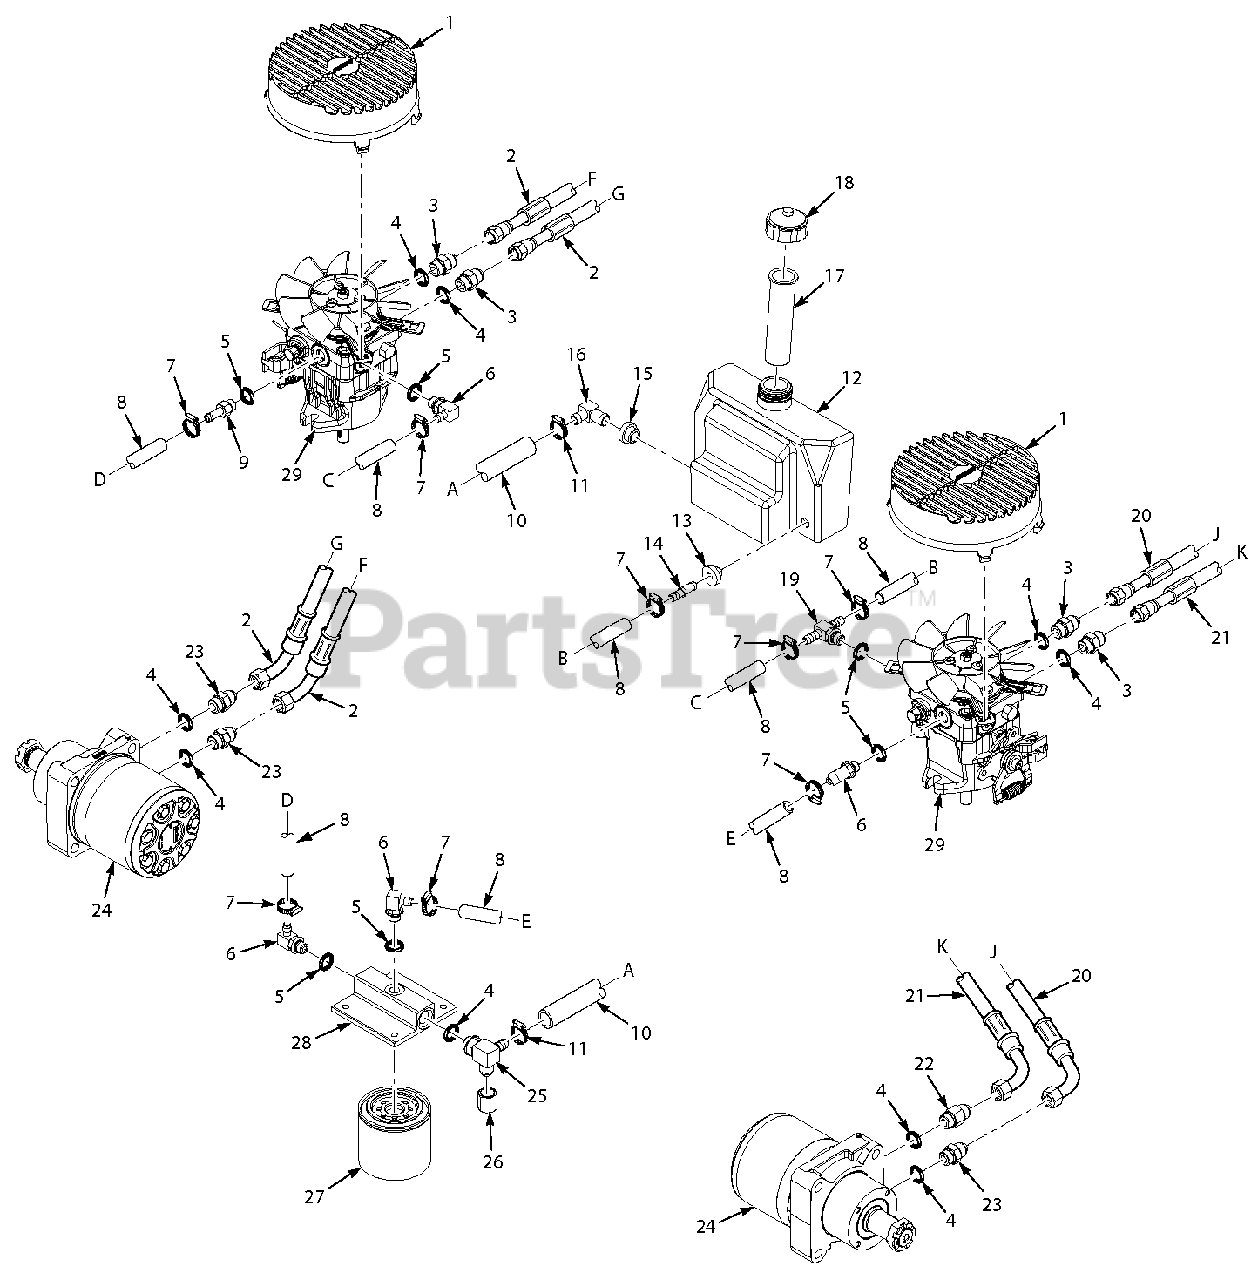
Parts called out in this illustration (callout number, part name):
1	Fan Cover, Pump
2	Hose Assembly
3	Fitting, 1/2" JIC x 1/2" O-Ring
4	O-Ring, 3/4"
5	O-Ring, 7/16"
6	Elbow, 90 Degree 9/16" O-Ring x 3/8" Hose
7	Hose Clamp, .69" Dia.
8	Hose, 3/8" Pushlock (order by inch)
9	Fitting, 9/16" O-Ring x 3/8" Hose
10	Hose, 1/2" Pushlock (order by inch)
11	Hose Clamp, .87" Dia.
12	Hydraulic Tank Assy
13	Bushing
14	Fitting, Straight
15	Bushing
16	Fitting
17	Insert, Filler Neck
18	Cap, Hydraulic Tank
19	Tee Fitting, O-Ring to Barb
20	Hose Assembly
21	Hose Assembly
22	Fitting, 1/2" JIC x 5/8" O-Ring (LH Wheel Motor - Upper Port Only)
23	Fitting, 1/2" JIC x 5/8" O-Ring
24	Wheel Motor, Parker
25	Tee, 3/4" O-Ring x JIC x 1/2" Hose
27	Oil Filter
28	Oil Filter Base
29	Pump, LH (PK-3KCC-GA1F-XXXX)
29	Pump, RH (PK-3HCC-GA1F-XXXX)
